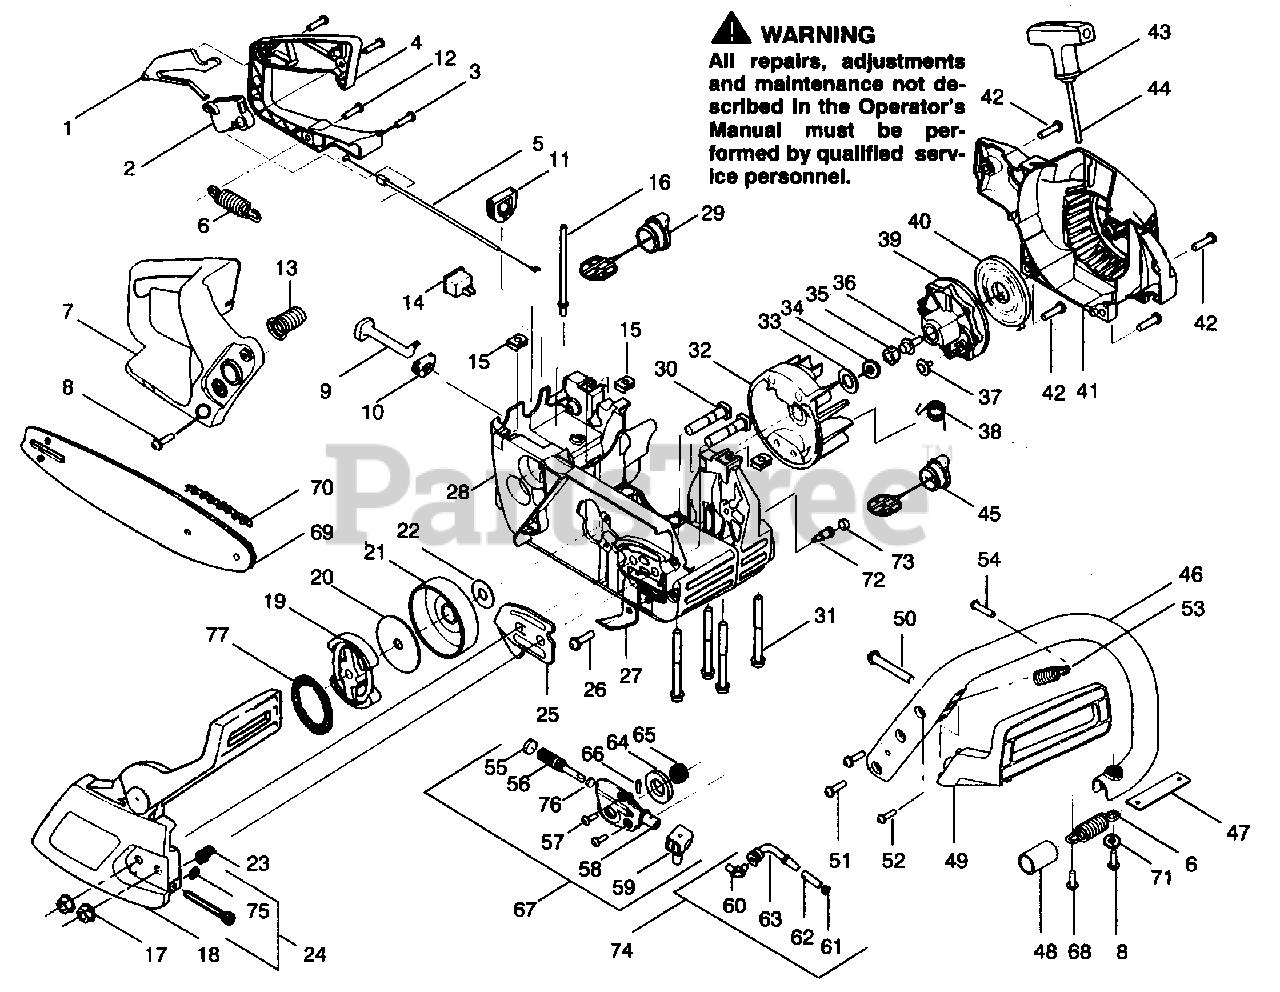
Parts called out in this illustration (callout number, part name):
1	Throttle Lockout
2	Throttle Trigger
4	Cover-Rear Handle
5	Throttle Cable
6	Spring
7	Rear Handle
9	Choke Knob
10	Grommet-Choke Knob
11	Grommet-Throttle Cable
13	Spring Ass'y.
14	Ignition Switch
15	Nut-"U" Type
16	Fuel Line Kit (Large Dia.)
17	Nut-Bar Mounting
18	Chain Brake Kit
19	Clutch Ass'y. (Inc. 77)
20	Clutch Washer
21	Clutch Drum Ass'y. w/Bearing
22	Washer-Thrust
23	Pin-Bar Adjusting
24	Bar Adjusting Kit (Inc. 75.)
25	Plate-Bar Mounting
26	Screw
27	Chain Catcher
28	Chassis Ass'y. (Inc.16,29,30,45,72-73; & from INTERNAL POWER UNIT: 2,16,31)
29	Fuel Cap Ass'y.
30	Bolt-Bar
32	Flywheel Ass'y.
34	Lockwasher
38	Spring-Starter Dog
39	Starter Pulley
40	Recoil Spring
41	Fan Housing
43	Starter Handle
44	Rope Kit
45	Oil Cap Ass'y.
46	Front Handle
47	Limiter Strap-Isolator
48	Isolator Sleeve
49	Handguard
53	Spring Ass'y.
55	Dust Plug
56	Gear Ass'y.
58	Oil Pump Body
59	Seal Block
60	Fitting-Elbow
61	Plug-Oil Filter
62	Oil Filter
63	Pick-up Tube
64	Dust Seal
65	Worm Gear
66	Pin-Dowl
67	Oil Pump Kit (Inc. 55-59, 66 & 76)
70	Chain-16"
71	Washer-Flat
72	Check Valve
73	Plug-Oil Vent
74	Oil Pick-up Ass'y (Inc. 60-63)
75	Retainer-Bar Adjust.
76	O-Ring Oiler
77	Spring-Clutch
